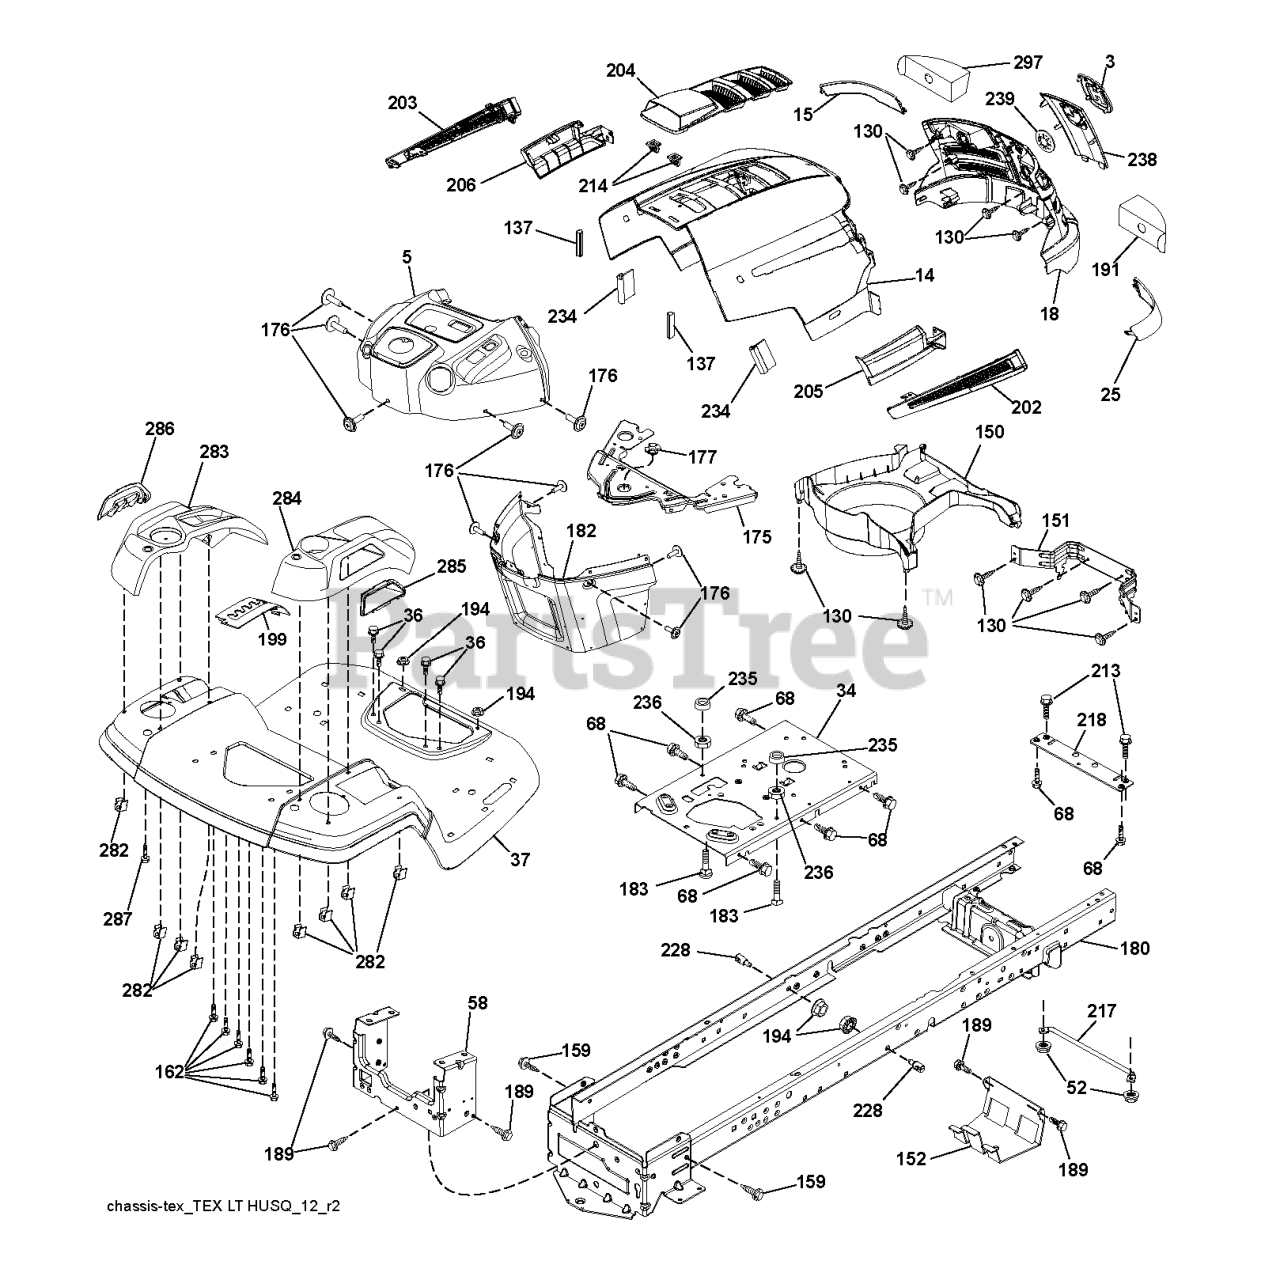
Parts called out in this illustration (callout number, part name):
3	RP LOGO
5	DASH
14	HOOD
15	LENS.HUSQVARNA LT.LH
18	RP GRILLE/LENS ASM.
25	LENS.HUSQVARNA LT.RH
34	PLATE.ENGINE.WELDED.CHASSIS
36	SCREW 5/16"
37	RP FENDER.TLT.FS.W/CPH.422
52	LOCKNUT
58	DRAWBAR UPPER 2PC SMALL FENDER
68	Screw 5/16-18 x 1/2 Hex, Self Tapping 5/16-18 x 1/2
130	SCREW.#10 X 0.750.BOS
137	BUMPER DASH
151	BRACKET PIVOT
152	SHIELD.BROWNING.W/TEX
159	SCREW, 3/8-16X3/4
162	SCREW.HI-LO.CONSOLE
175	CROSSMEMBER
176	SCREW.#10-24X5/8.RN.QU
177	BUSHING STEERING
180	CHASSIS.WLDMNT.14GA.2PC.18".TI
182	DASH.LOWER.PREDATOR LT
183	BOLT.5/16-18X1-1/4 FULL.THREAD
189	SCREW
191	INSERT.REFLECTIVE.RH.
194	NUT LOCK HEX FLANGE 5/16-18
199	PLATE.DECK.LIFT.HUSQ.LT
202	VENT SIDE HOOD LH
203	VENT SIDE HOOD RH
204	VENT TOP HOOD
205	SKIRT SIDE RH
206	SKIRT SIDE LH
213	BOLT
214	CLIP.RETAINER.TINNER.
217	ROD.PIVOT.HOOD
218	X-PIECE.HOOD.STOP.NON/
228	STUD.FASTNER.W/ANTI-ROTATE
234	BUMPER.HOOD.TEX.HUSQVARNA
235	SPACER FENDER
236	NUT.CENTERLOCK.5/16-
238	TRIM
282	CLIP.RETAINER.CONSOLE.LT.HUSQ
283	CONSOLE.DECK.LIFT.HUSQ.N/FR.GR
284	CONSOLE.CNTRL.
285	CONSOLE INSERT RH
286	CONSOLE.INSRT.LH.HUSQ.LT.BLACK
287	SCREW 1/4X20
297	INSERT REFLECTIVE
